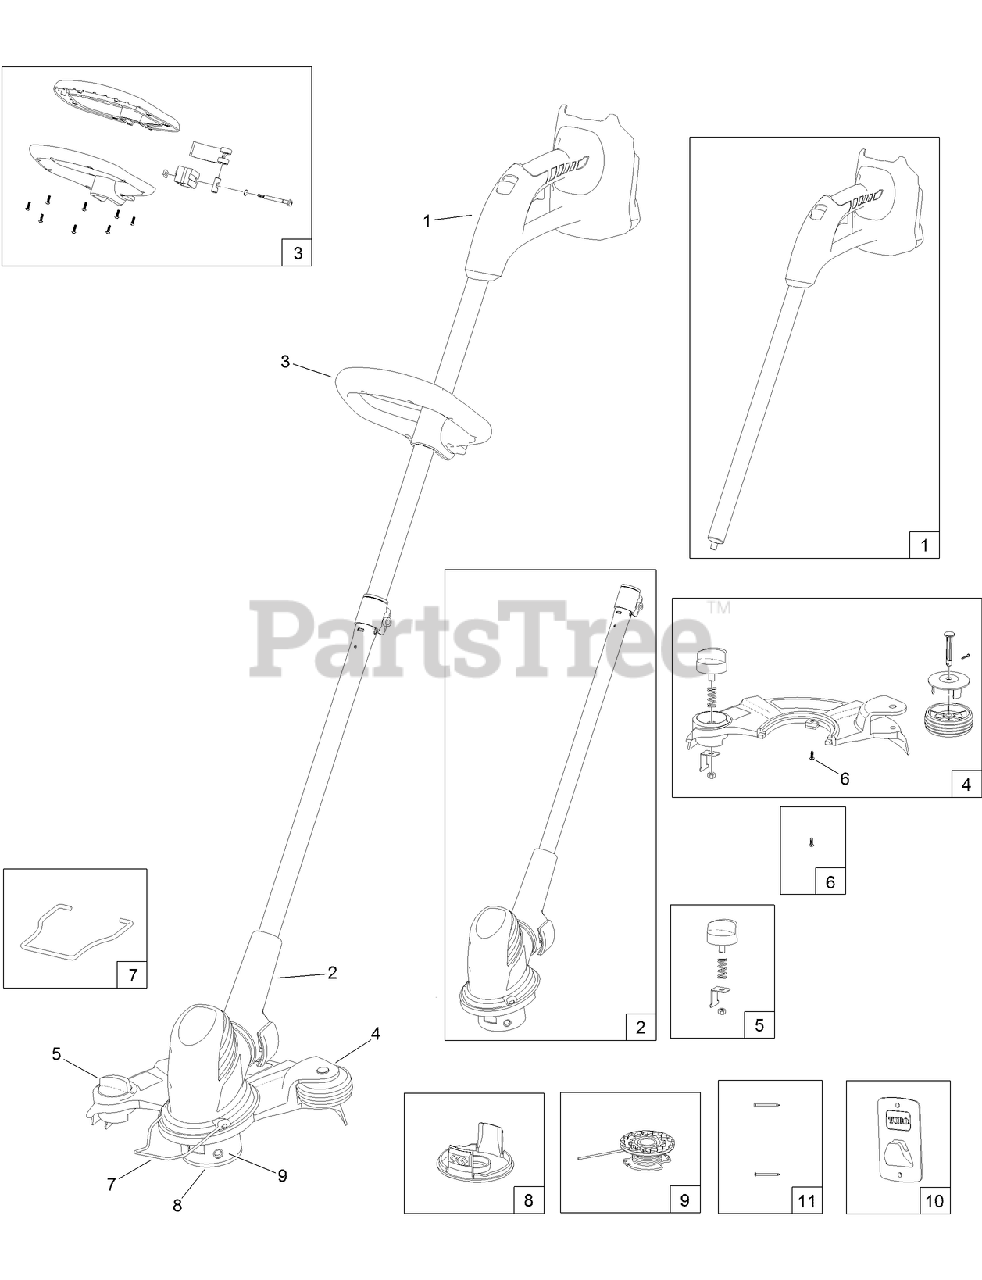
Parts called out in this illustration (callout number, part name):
2	LOWER MOTOR HOUSING ASM
3	ASSIST HANDLE ASM
4	GRASS SHIELD ASM
5	KNOB-SAVER, POWER
7	CLIP-GUIDE, EDGER
8	CAP-RETAINER, SPOOL
9	SPOOL-TRIMMER, 12 INCH
10	BRACKET-MOUNT, WALL
